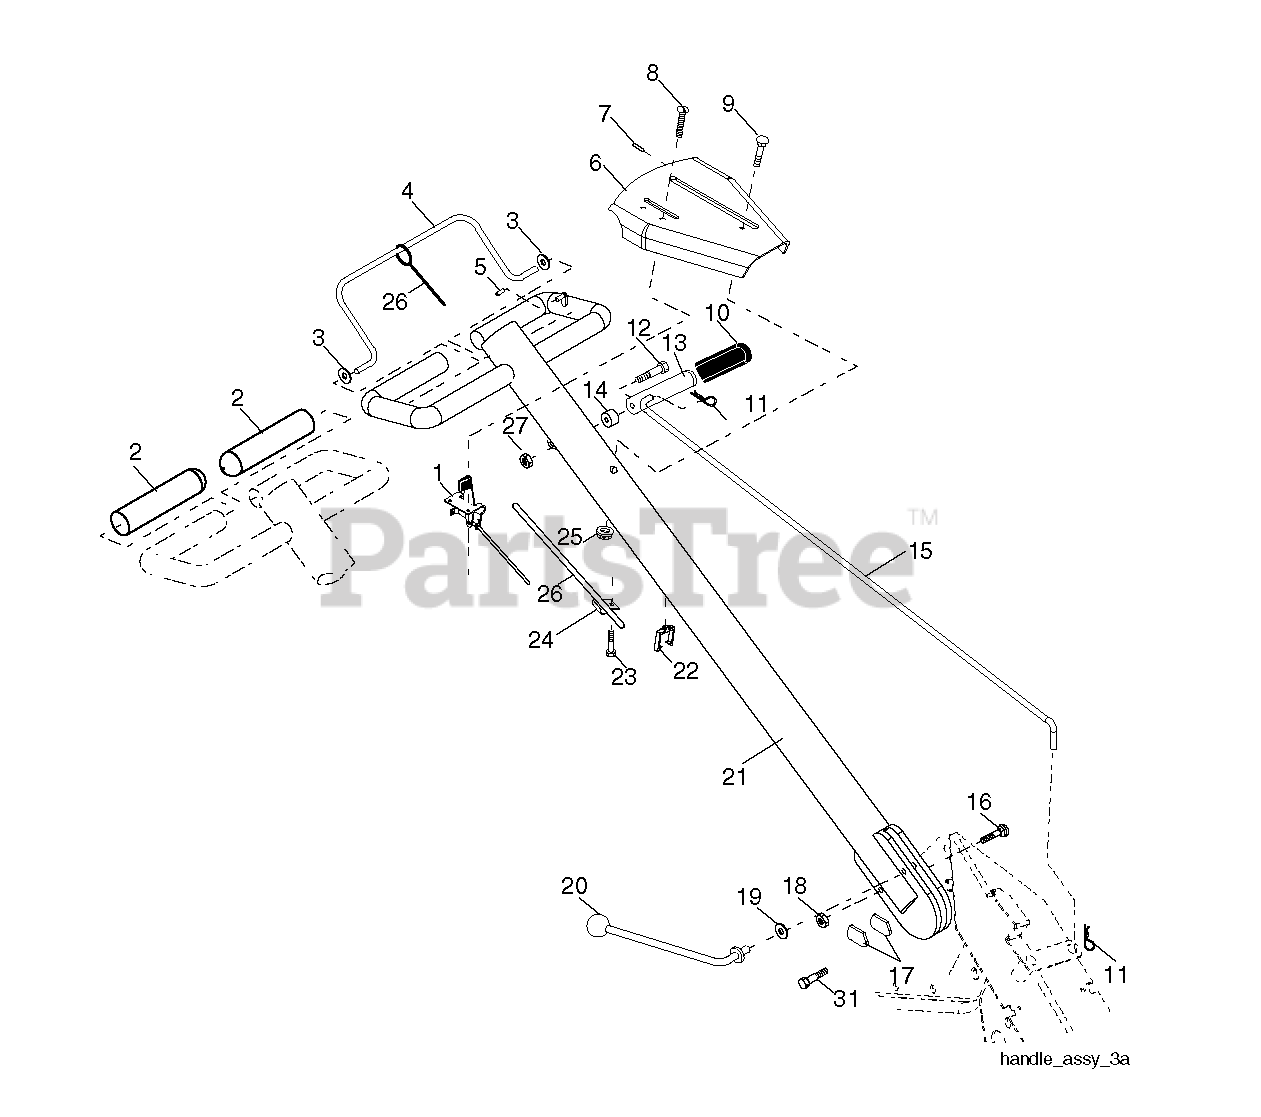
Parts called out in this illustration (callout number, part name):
1	THROTTLE.CONTROL.RT
2	GRIP.HANDLE.TILLER
3	Handle Grommet
4	BAR ASSEMBLY, CONTROL
5	VINYL CAP TI
6	PANEL, CONTROL
7	BUSHING SPLIT
8	SCREW
9	BOLT.5/16-18X2.5
10	GRIP, HANDLE
11	RETAINER M
12	SHOULDER BOLT ST
13	HANDLE.SHIFT.TILLER
14	GROMMET.RUBBER.CRT.TILLER
18	LOCKNUT
19	WASHER CRT
20	LEVER.LOCK.CRT
23	TAPPING SCREW
24	CONDUIT CLIP T
25	LOCKNUT-FLANGE 5/16-18
27	NUT T
